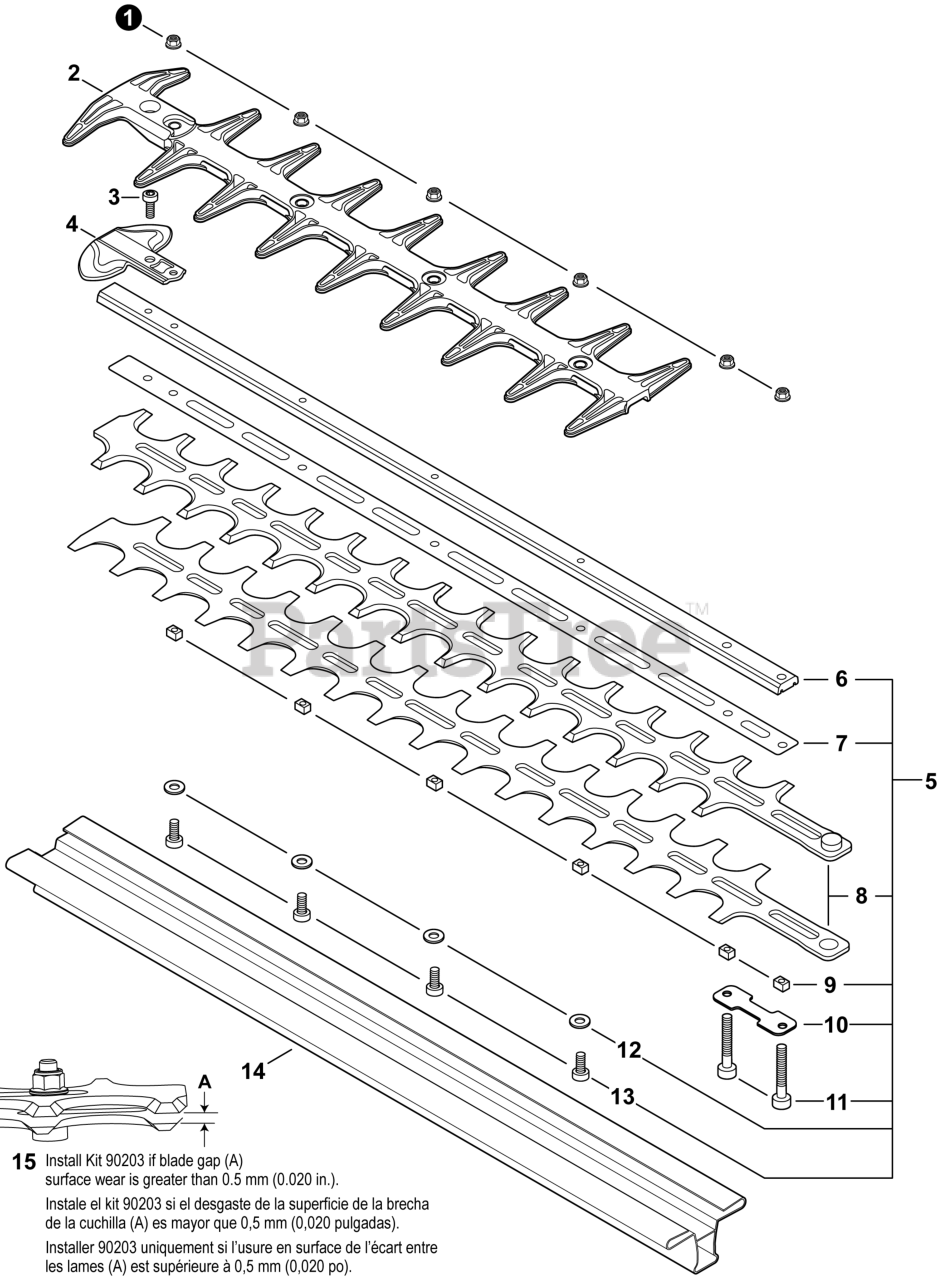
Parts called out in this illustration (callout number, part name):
1	NUT, FLANGE M5
2	GUARD, CUTTER BLADE
3	BOLT, TORX 5x8
4	GUARD, TIP
5	CUTTER ASSY, 20"
6	SUPPORT, CUTTER 20"
7	PLATE, CUTTER 20"
8	CUTTER, 20"
9	GUIDE, BLADE 5
10	PLATE, EYE
11	BOLT, TORX 5x30
13	BOLT, TORX 5x25
14	SCABBARD - BLACK
15	BLADE KIT, ADJUSTABLE
